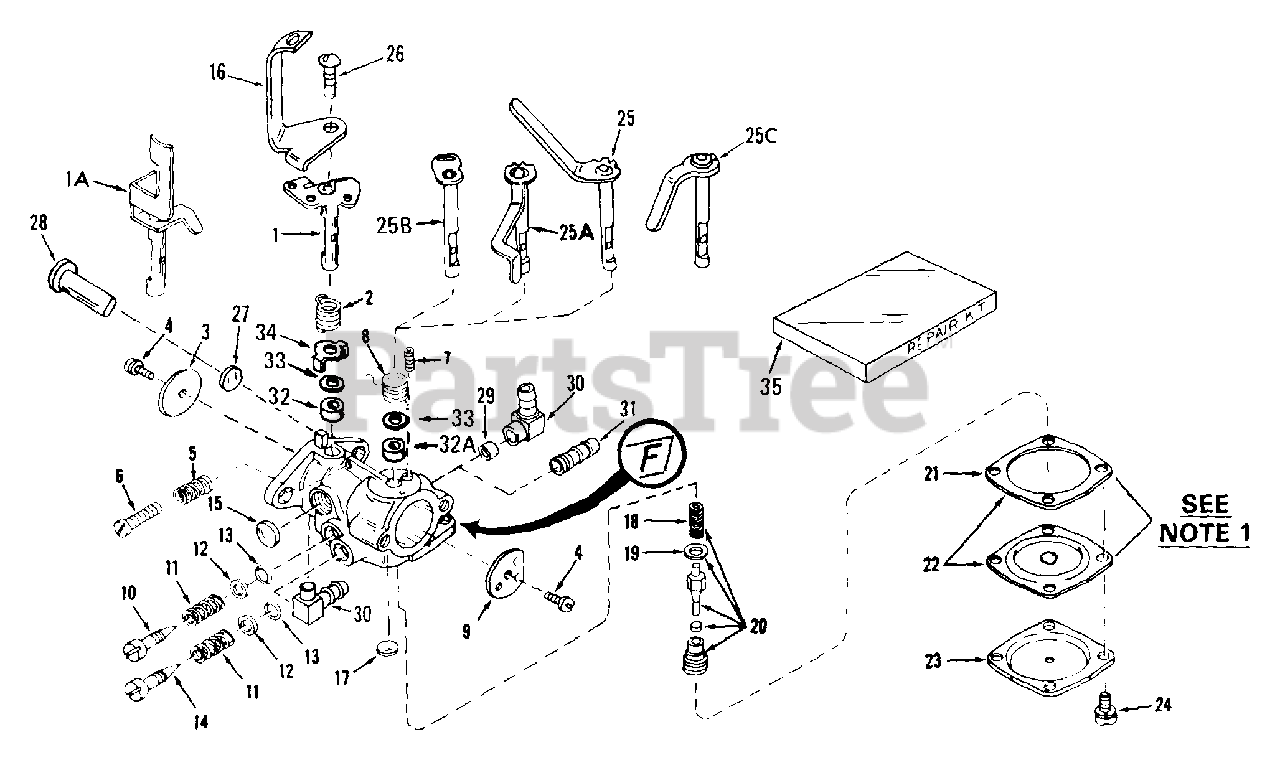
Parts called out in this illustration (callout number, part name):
1	"Shaft & Lever Assy., Throttle
2	Spring, Return
3	Shutter, Throttle
4	Screw, Throtttle & Choke shutter
5	Spring, Regulating screw
6	Screw, Idle regulating
7	Spring, Choke positioning
9	Shutter, Choke
10	Screw, Idle adjustment
11	Spring, Adjustment screw
12	Washer, Adjustment screw
13	"O" Ring, Adjustment screw
14	Screw, Main adjustment
15	Plug, Welch
17	Plug, Welch
18	Spring, Valve
19	Gasket, Valve Seat
20	Inlet Needle, Seat, Gasket & Spring A ssy.
21	Gasket, Diaphragm
22	Diaphragm Assy. (Incl. No. 21)
23	Cover, Diaphragm
24	Screw, Cover
25	Shaft & Lever Assy., Choke
30	Fitting, Fuel inlet
35	Repair Kit
